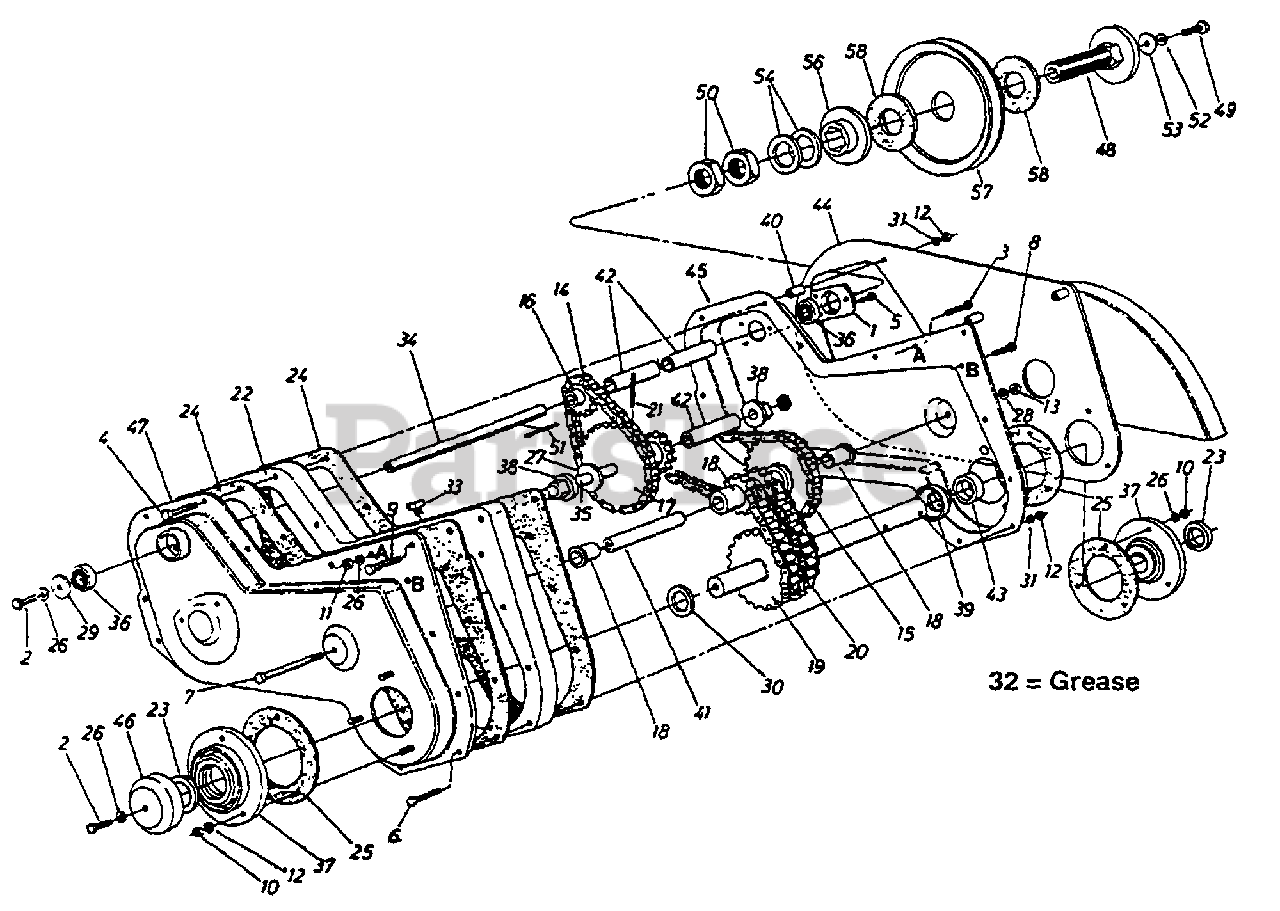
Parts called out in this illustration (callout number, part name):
1	Bearing Housing 1-3/8" Dia.
2	Hex Bolt 5/16-18 x .88" (Spec.)
3	Hex Bolt 5/16-18 x 1.5" Lg.
4	Hex Bolt 1/4-20 x 2.75" Lg.
5	Hex S-Tap Scr. 1/4-20 x .5" Lg.
6	Hex Bolt 1/4-20 x 1.5" Lg.
7	Hex Bolt 3/8-16 x 4.5" Lg.
8	Hex Scr. 1/4-20 x 1.5" Lg.
9	Hex TT-Tap Scr. 5/16-18 x 1.75"
10	Hex L-Nut 5/16-18 Thd.
11	Hex Nut 5/16-18 Thd.
12	Hex Nut 1/4-20 Thd.
13	Hex Nut 3/8-16 Thd.
14	#41 Chain 1/2" Pitch x 34 Links - Endless
15	#42 Chain 1/2" Pitch x 48 Links - Endless
16	Sprocket 10 Tooth .5" Pitch
17	10 8 28 Teeth Sprocket Ass'y.
18	8-2 & 28 Sprocket Sleeve Ass'y.
19	18-2 Sprocket Shaft Ass'y.
20	#50-2 Chain 5/8" Pitch x 28 Links - Endless
21	Spring Pin Spir. 1/4" Dia. x 1.5" Lg.
22	Spacer Block - Tiller Housing
23	Oil Seal 1-1/4" Dia.
24	Gasket for Tiller Housing
25	Gasket for Brg. Housing
26	L-Wash. 5/16" I.D.
27	Fl-Wash .64" I.D. x 1.24" O.D.
28	L-Wash. 3/8" I.D.- H.D.
29	Fl-Wash .344" I.D. x 1.125"
30	Special Washer
31	L-Wash. 1/4" l.D.
33	Vent Plug
34	Jack Shaft.525" I.D. x 7.78"
35	Sprocket Shaft .63" Dia. x 5"
36	Ball Brg .62" l.O. x 1.38" O.D.
37	Bearing Housing - 1-1/4
38	Hex Flange Brg.
39	Spacer 1.25" I.D. x 2.0" O.D.
40	Spacer .9" Lg.
41	Spacer 3.44" Lg.
42	Spacer .62" x
43	Spacer .5" Lg.
46	Dust Cap
49	Hex Bolt 5/16-18 x 1.25" Lg. Grade 5
50	Hex Jam Nut 1.0-14 x 28 Thd.
51	Sq. Key 3/16 x 1.5" Lg.
52	L-Wash. 5/16" i.D.
53	Fl-Wash .344" I.D. x 1.125"
54	Bell-Wash. 1.0" I.D. x 2.0"
56	Floating Disc 3-1(4" O.D.
57	5/8 V-Pulley 1.5" I.D. x 6.5"
58	Friction Pad 3-1/4" O.O. x 1-3/4" I.D.
